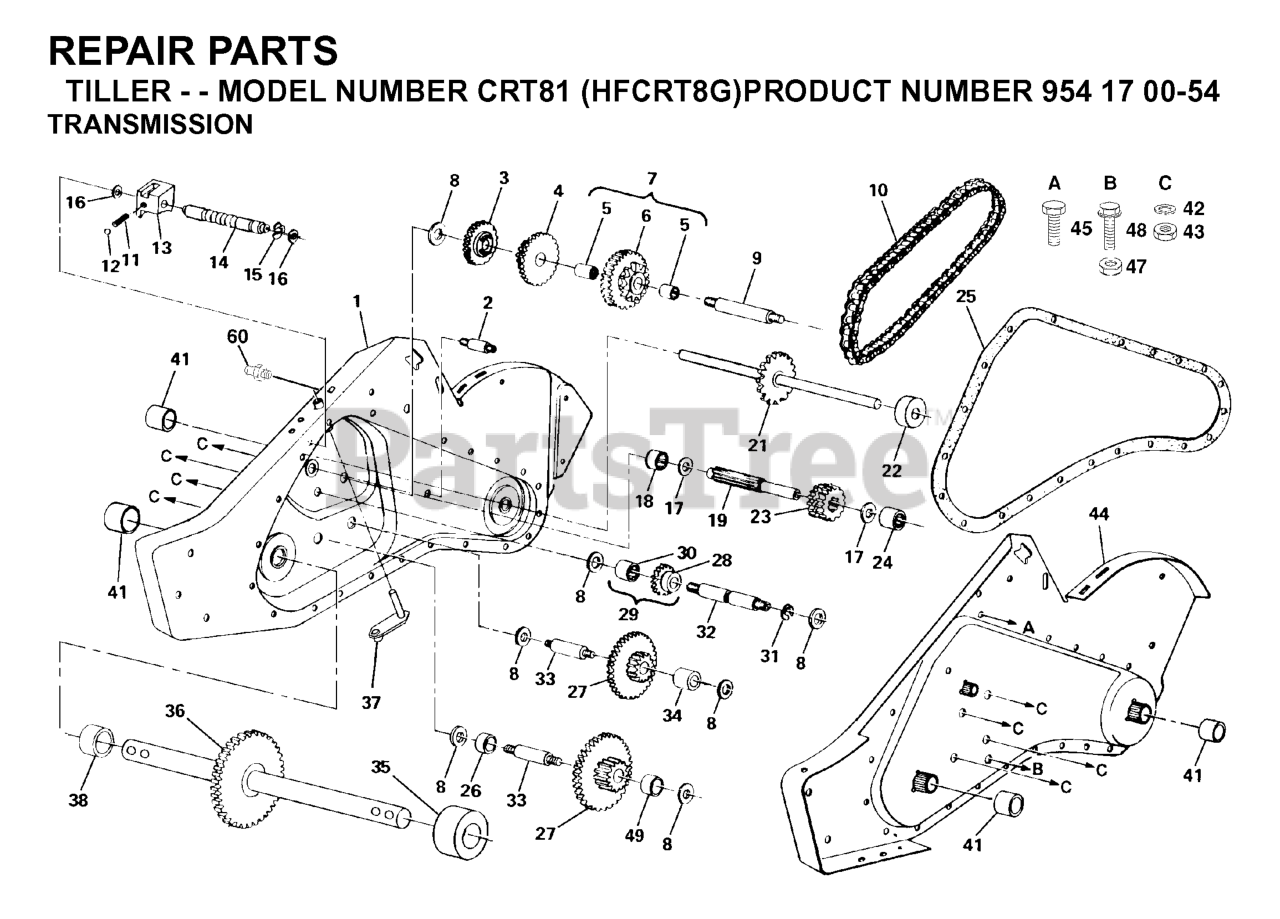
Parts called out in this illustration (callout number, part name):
1	GEARCASE ASM.RH.W/BEARING 2002
2	SPACER.GEARCASE
3	GEAR.REVERSE.8HP
5	BEARING.NEEDLE.CRT
6	SPROCKET ASMBLY, TINE
7	SPROCKET ASMBLY W/BEARINGS
9	SHAFT.REDUCTION.TILLER
10	CHAIN.ROLLER.TILLER
11	SPRING-SHIFT CRT
12	STEEL BALL KIT
13	SHIFT FORK TI
14	SHAFT.SHIFT.1.00 PINION
16	WASHER, SEAL (2 2)
17	THRUST WASHER
18	BEARING TI
19	SHAFT INPUT
21	SHAFT TINE CRT
22	SPACER 1.008X1-3/4X.645
23	GEAR.PINION
24	NEEDLE BRNG LT
25	RP GASKET, GEARCASE
27	GEAR, CLUSTER CRT
28	REVERSE GEAR
29	GEAR ASMBLY, REVERSE IDLER
30	NEEDLE BEARING TI
32	SHAFT, REVERSE IDLER
33	SHAFT, REDUCTION
34	SPACER.765 X 1.12 X .380.
35	SPACER, GROUND DRIVE RH
36	SHAFT ASSY CRT
37	BRACKET ASM.SHIFT.CRT
38	SPACER, GROUND DRIVE
41	SEAL ASM, OIL
42	LOCKWASHER
43	NUT.ASF.HEX.7/16
44	GEARCASE ASM.LH.W/BEARING 2002
45	SCREW
48	SCREW 5/16-18X4
60	ZERK M
